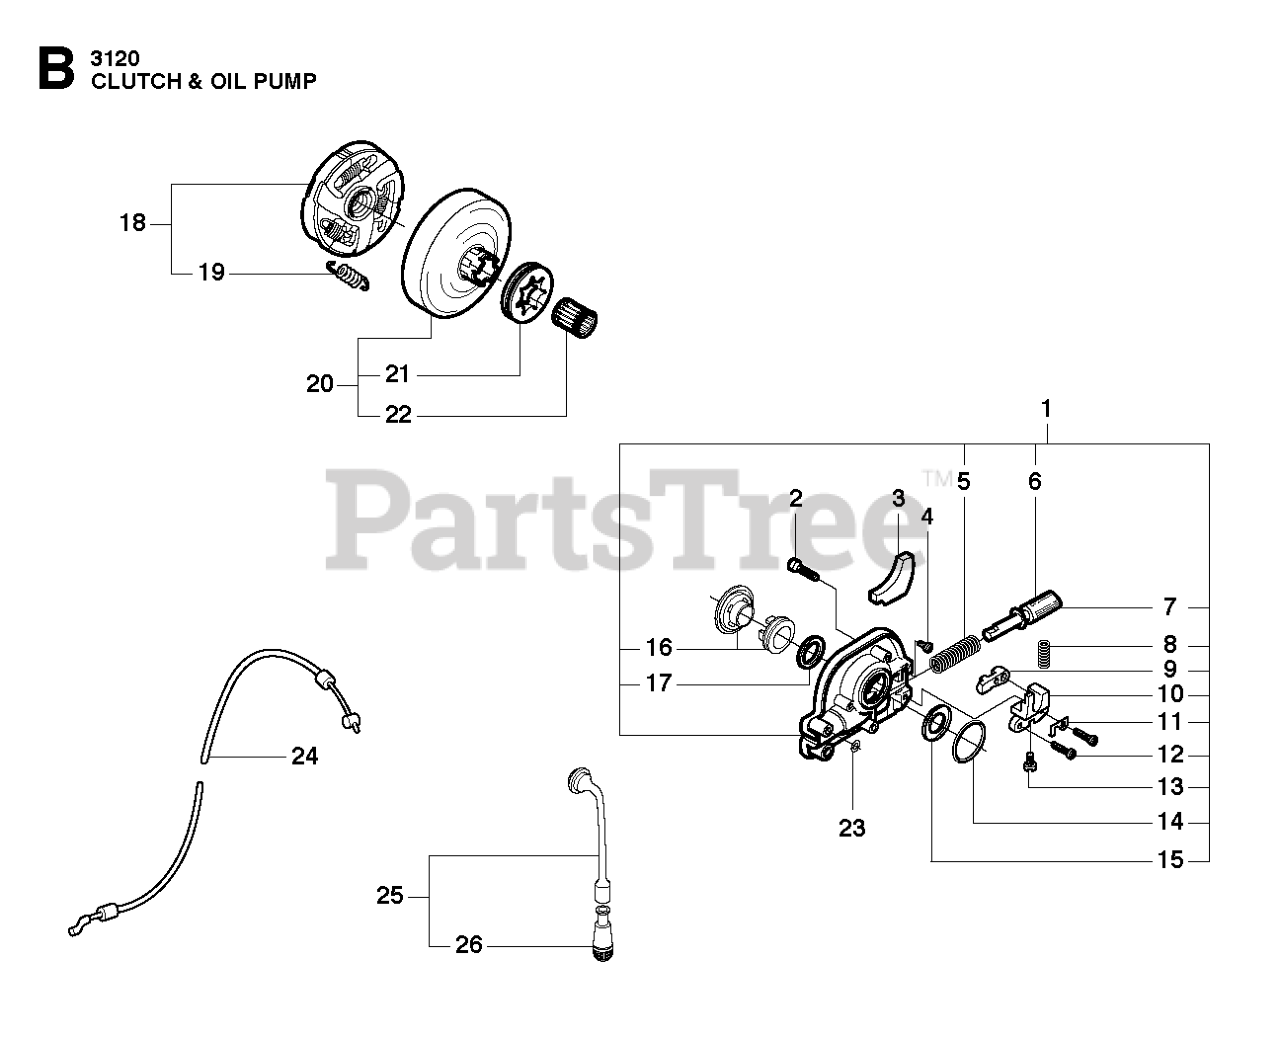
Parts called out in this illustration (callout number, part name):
2	SCREW MC6S 4X20
5	RECOIL SPRING
7	PUMP PLUNGER
15	SEALING RING
18	CLUTCH CPL
19	CLUTCH SPRING
20	CLUTCH DRUM
21	22270 RIMSPROCKET
22	SUPPORT BUSHING
26	OIL SCREEN
